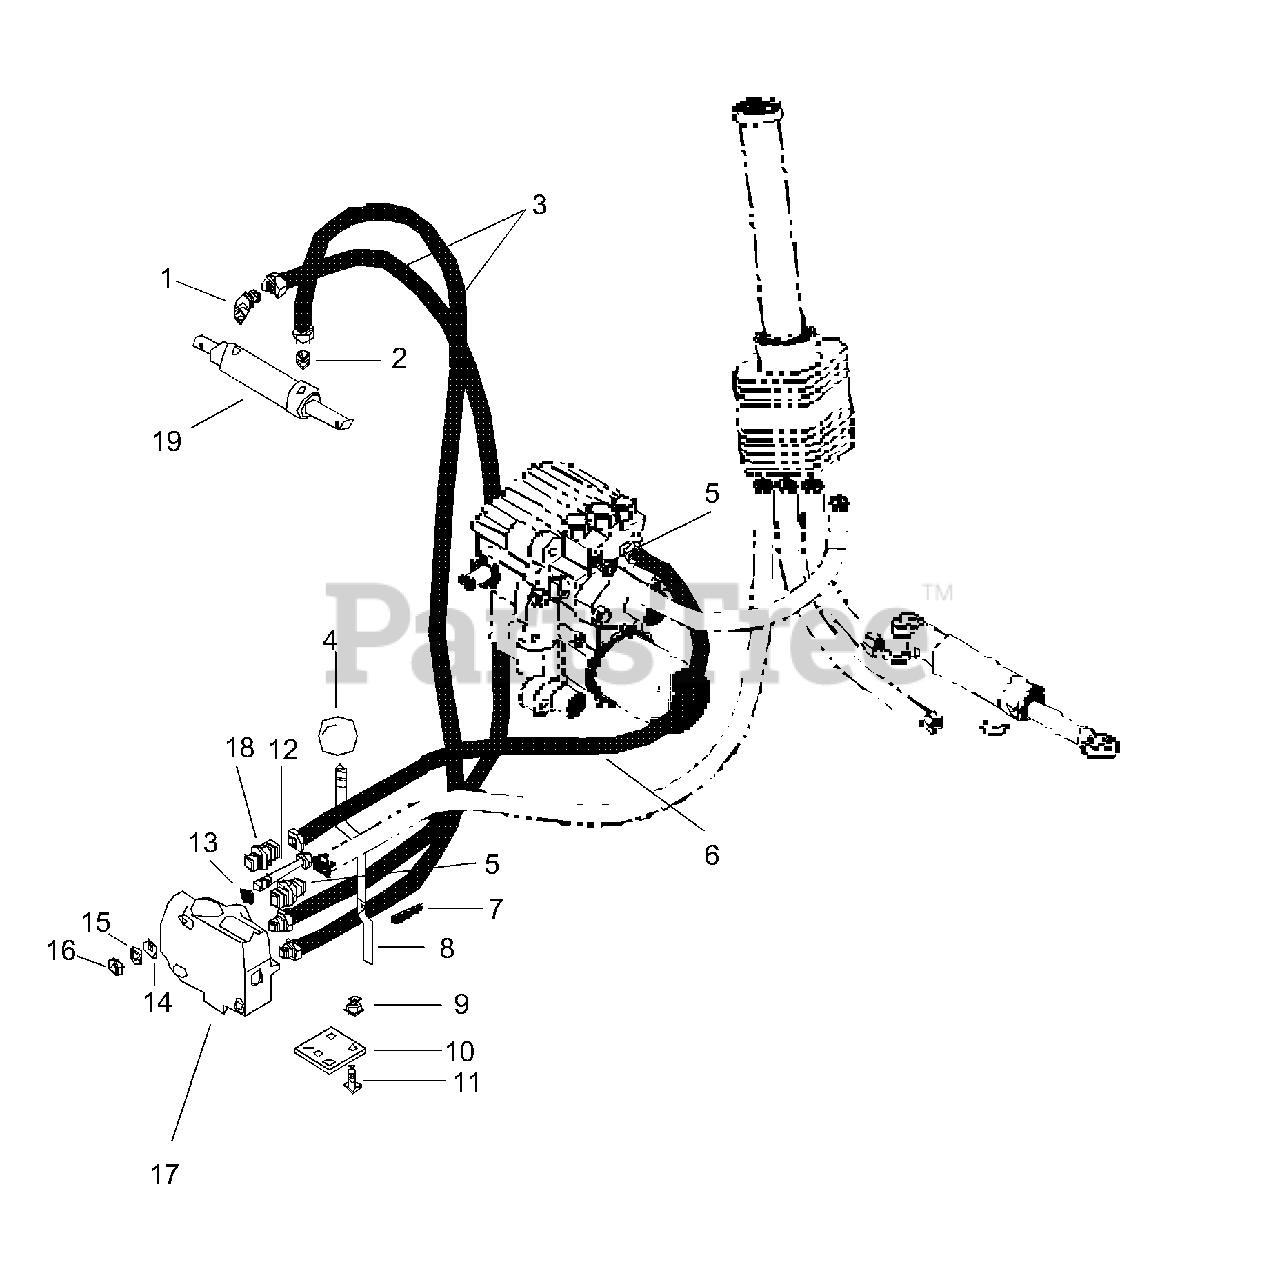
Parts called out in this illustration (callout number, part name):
1	Adapter 9/16 to 1/4
2	Adapter
3	Hydraulic Hose
4	Knob-Steering Lock
5	Adapter-Pipe
6	Hydraulic Hose
7	Pin-Groove .250 x .75
8	Control Rod
9	Nut-Flange-Locking .31-18
10	Pivot Bracket
11	Bolt-Round Head Square Neck .31-18 x .50
12	Bolt-Hex .25-20 x 2.25 Grade 5
13	Washer-Flat-Steel .265 x .50 x .087
14	Washer-Flat-Steel .281 x .620 x .065
15	Washer-Lock .250 x .077
16	Nut-Hex .25-20
17	Hydraulic Control Valve
18	Connector
19	Cylinder Assembly Lift
